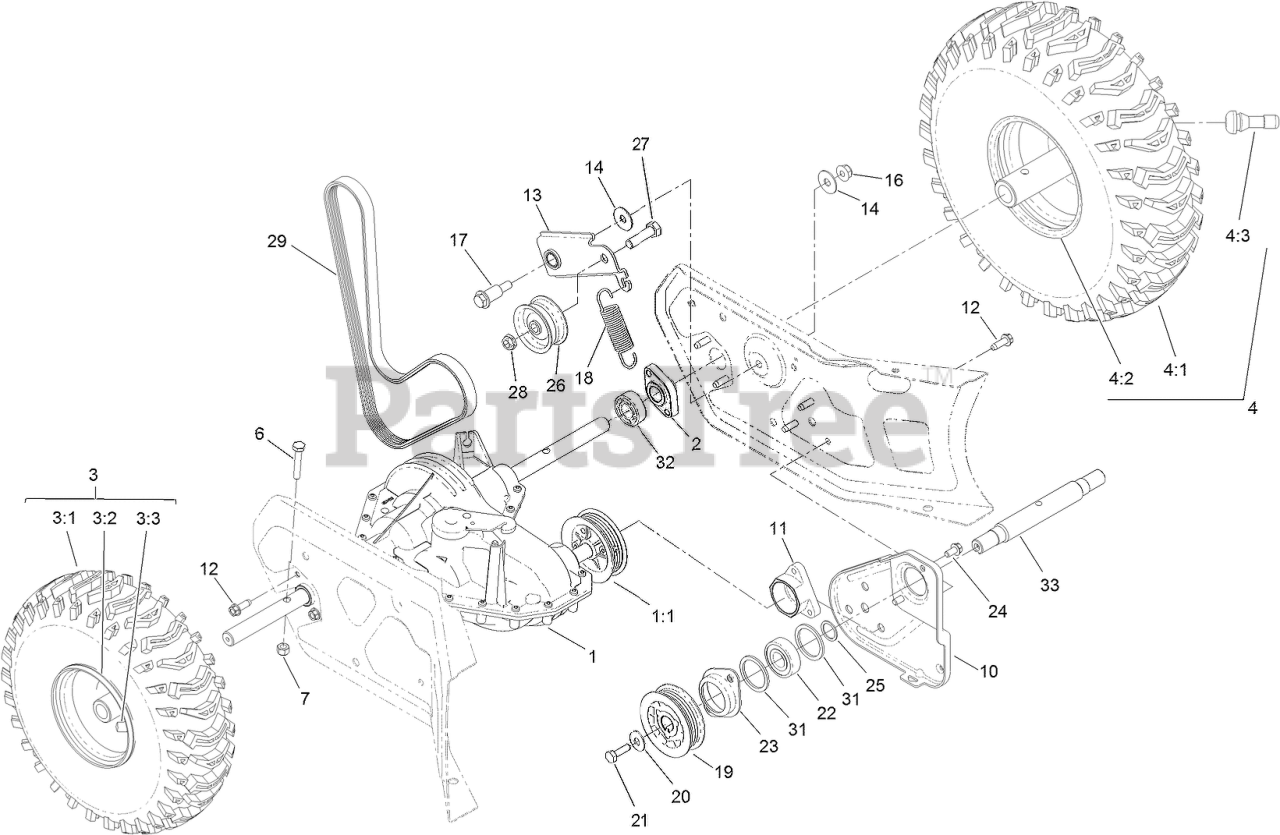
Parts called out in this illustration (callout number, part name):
1	TRANSMISSION
1:1	PULLEY REPAIR KIT
2	BEARING-AXLE
3	RH WHEEL AND TIRE ASM
3:3	STEM-VALVE
4	LH WHEEL AND TIRE ASM
4:3	STEM-VALVE
6	SCREW-HH
7	NUT-LOCK, NI
10	PLATE-SUPPORT, JACKSHAFT
11	SUPPORT-BEARING
12	SCREW-HWHTF
13	IDLER-TRACTION
14	WASHER
16	NUT-HF, NI
17	BOLT-SHOULDER, HHF
18	SPRING-EXTENSION
19	PULLEY-JACKSHAFT
20	WASHER-BELLEVILLE
21	SCREW-HH
22	BEARING-BALL
23	RETAINER-BEARING
24	SCREW-HWH
25	WASHER-THRUST
26	PULLEY-IDLER, FLAT
27	SCREW-HH
28	NUT-LOCK, NI
29	BELT-POLY V
31	WASHER-RUBBER
32	SPACER-AXLE
33	JACKSHAFT
